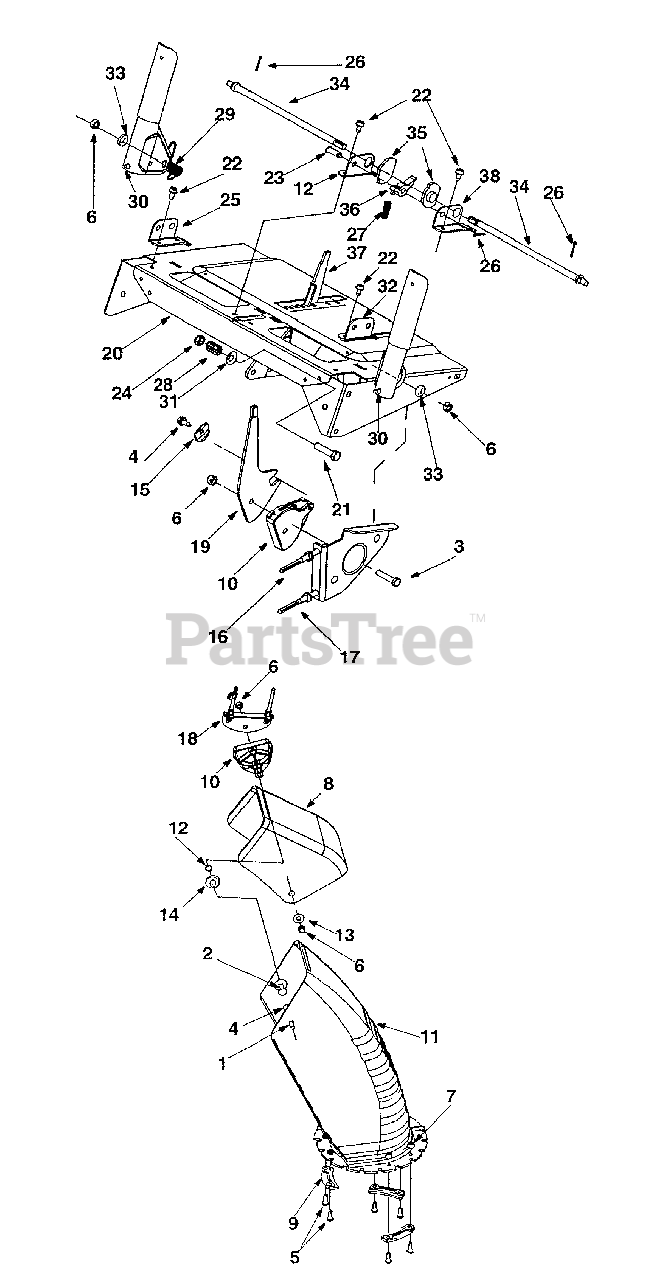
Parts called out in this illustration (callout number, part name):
1	Carriage Screw
2	Carriage Bolt 5/16-18 x 1.75"
3	Hex Bolt 5/16-18 x 1.5"
4	Hex AB Screw 1/4-14 x .625"
5	Hex Screw 1/4-20 x .75"
6	Hex Lock Nut
7	Hex Flange Lock Nut
8	Upper Chute
9	Chute Flange Keeper
10	Cable Guide: Chute Tilt
11	Lower Chute
13	5/16 Washer
14	Flat Washer
15	Special Washer
16	Chute Control Cable
17	Chute Cable w/Clip
21	Hex Bolt 3/8-24 x 1.5"
22	TT Screw 1/4-20 x 0.5"
23	Clevis Pin
26	Cotter Pin
29	Torsion Spring
30	Rubber Bumper
31	Bell Washer
33	Special Washer
35	Cam: Handle Lock
36	Pawl: Handle Lock
